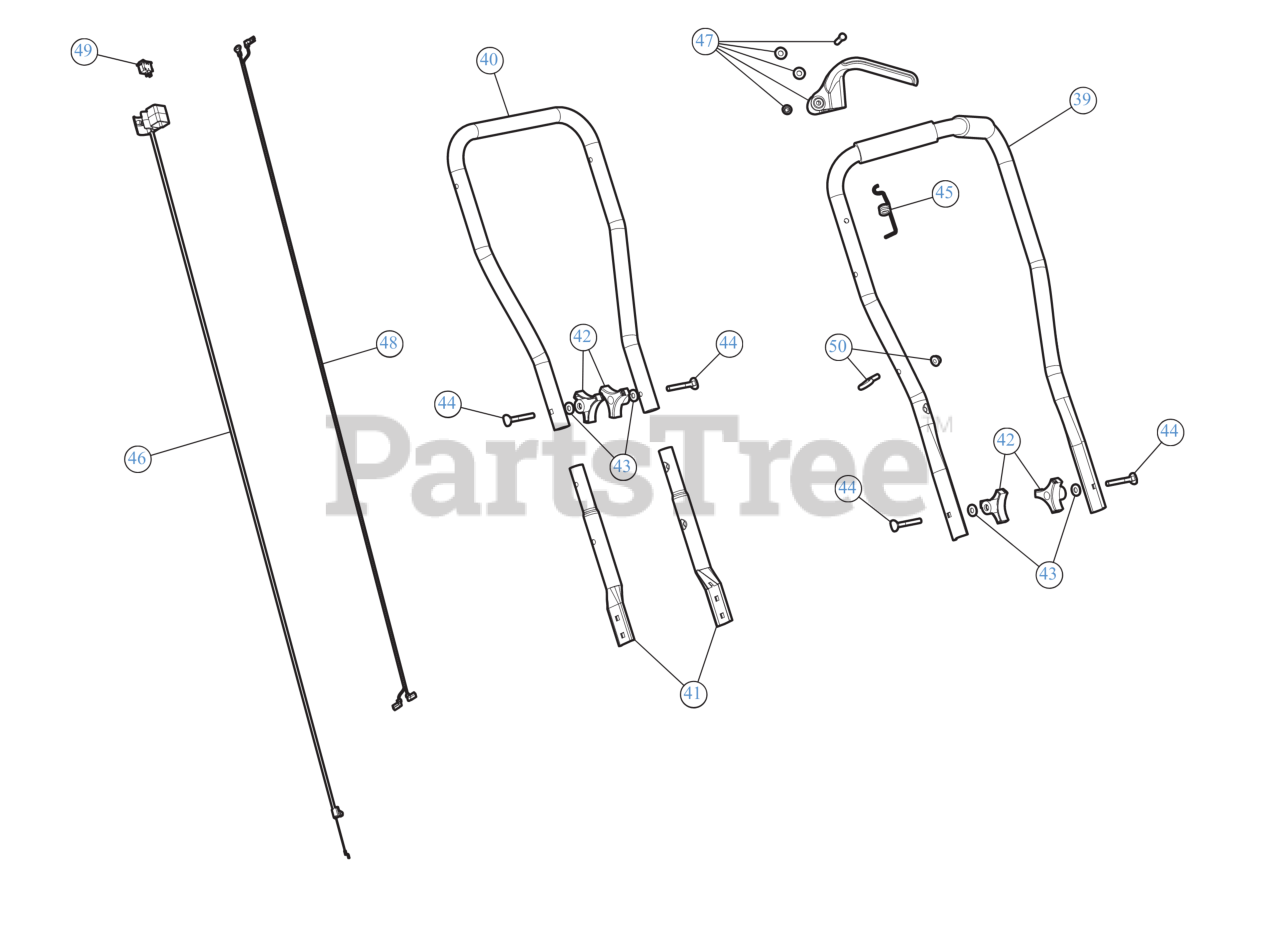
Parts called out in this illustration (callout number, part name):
39	HANDLE UP
40	HANDLE MID
41	HANDLE EXT
42	KNOB, 3-PRONG ¼ "-
43	WASH, FLAT SPECIAL
44	BOLT, CARRIAGE CRV
45	SPRING
46	THROTTLE CABLE
47	THROTTLE LVR W/HDW
48	WIRE LEAD
49	SW, MOMENTARY ON/O
50	ROPE GUIDE
